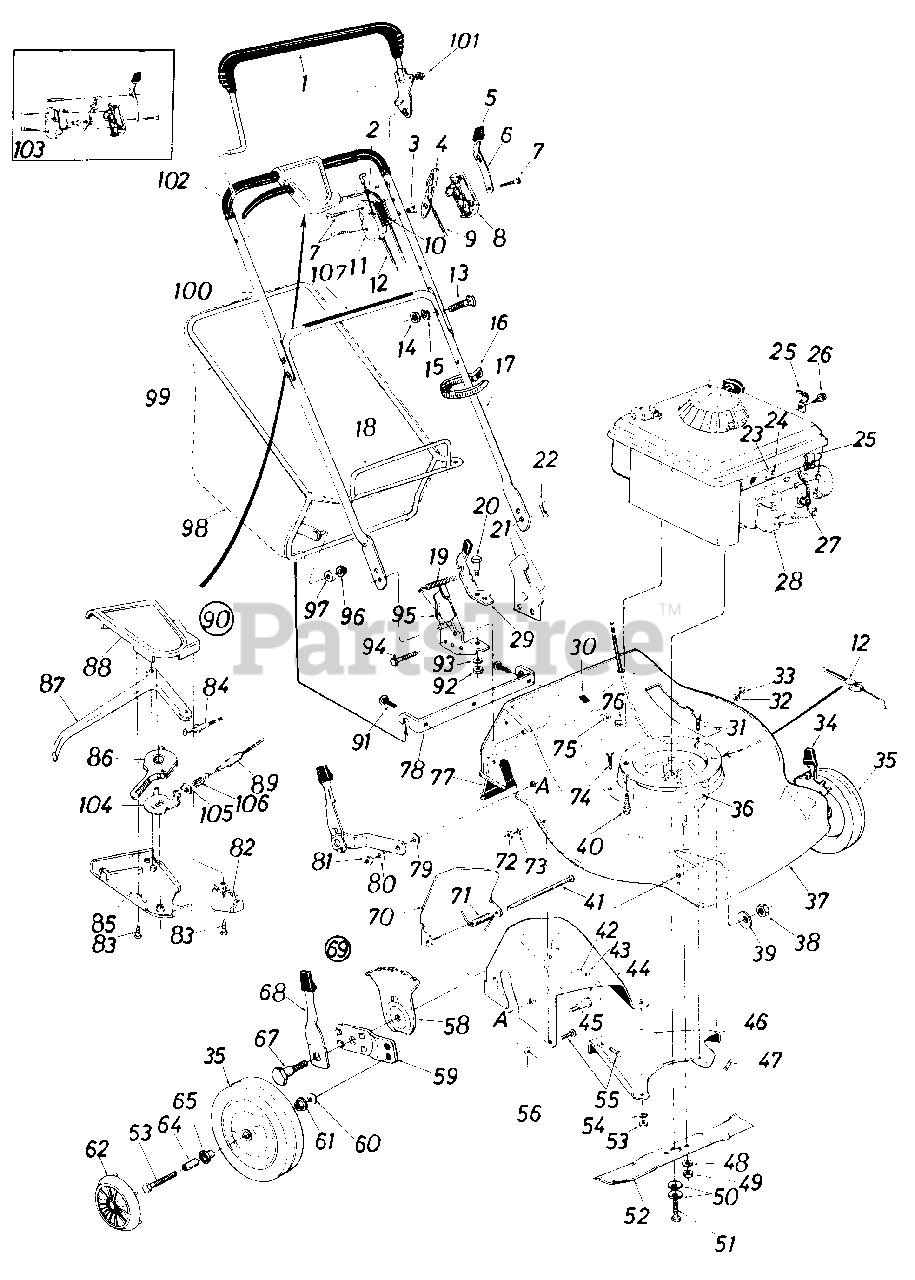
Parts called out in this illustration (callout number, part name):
1	L.H. Bail Ass'y.
2	Lock Pin
3	Control Disc Pin
4	Throttle Control Lever
5	Spring Lever Knob
6	Lockout Spring
7	Truss Mach. Hi-B Tap Scr. #12 x 1.50" Lg.
8	Control Panel Half
9	Throttle Control Wire-58"
10	Control Label
11	Clutch Panel Half
12	Clutch Cable 46" Lg.
13	Carr. Bolt 5/16-18 x 1.38"
14	Hex Nut 5/16-18 Thd.*
15	L-Wash. 5/16 I.D.*
16	Cable Tie
17	Lower Handle (Chrome)
20	Shld. Bolt .437" Dia. x .162
21	Handle Brkt. Ass'y.-L.H.
22	Hairpin Cotter 5/16" Dia.
23	Hex B-Tap Scr. #10 x .62"
24	Casing Clamp
25	Cable Clip
26	Hex B-Tap Scr. #10 x .38"
27	Spark Plug Insulator
28	Engine
29	Catcher Lock Lever w/Knob
31	Hex TT-Tap Scr. 1/4-20 x .75" Lg.
32	L-Wash. 1/4" I.D.
33	Hex Nut 1/4-20 Thd.*
34	Height Adj. Ass'y.-L.H.
35	Front Wheel Ass'y. Comp.
36	Blade/Brake Clutch Ass'y.-Comp.
39	Bell-Wash. .39" I.D. x 1.13"
40	Hex Wash. Hd. TT-Tap Scr. 3/8-16 x 1.0" Lg.
41	Hinge Pin
42	Hex Nut 1/4-20 Thd.*
43	L-Wash. 1/4" I.D.*
44	Rear Chute-R.H.
45	Shld. Bolt.500" Dia.
46	Rear Baffle-L.H.
47	Carr. Bolt 1/4-20 x .50" Lg.*
48	L-Wash. 3/8" I.D.*
49	Hex Nut 3/8-24 Thd.-Gr. 8
50	Bell-Wash. .40" I.D. x .88"
51	Hex Cl-Bolt 3/8-24 x 2.0" Lg. (Grade 8)
52	22" Blade
53	Hex Nut 1/4-20 Thd.*
54	L-Wash. 1/4" I.D.
55	Carr. Bolt 1/4-20 x .50" Lg.
56	Hex Sems Nut 1/4-20 Thd.
58	Height Adj. Plate
59	Wheel Pivot Bar
60	Bell-Wash. .40" I.D. x .88"
61	Bearing
62	Plastic Hub Cap
63	Axle Bolt
64	Spacer
65	Bearing
67	Shld. Bolt .50" Dia. x .430
68	Spring Lever Ass'y. w/ Knob
69	Height Adj. Ass'y.-R.H.
70	Chute Door
71	Torsion Spring
72	Hex Nut 1/4-20 Thd*
73	L-Wash. 1/4" I.D.*
74	Hex Bolt 1/4-20 x .88" Lg.
75	Fl-Wash. .285" I.D. x 1.25"
76	Hex Sems Nut 1/4-20 Thd.
77	Rear Flap
78	Grass Catcher Hitch Brkt.
79	Bell-Wash. .40" I.D. x 1.13"
80	Bell-Wash. .40" I.D. x .88"
81	Hex Jam Nut 3/8-16 Thd.
82	Cable Mounting Cap
83	Flat 'C"Sunk Hd. Tap Scr. #10 x .75" Lg.
84	S.P. Cable-53" Lg.
85	3-Sp. S.P. Control-Lower Cover
86	Shimano 3-Sp. Shift Lever
87	Control Lever
88	3-Sp. S.P. Control-Upper Cover
89	Shimano 3-Sp. Solid Shift Cable
90	Clutch Control Hsg. Comp.
91	Carr. Bolt 1/4-20 x .75" Lg.
92	Hex Nut 5/16-18 Thd.*
93	L-Wash. 5/16" I.D.*
94	Hex L-Wash. Hd. AB-Tap Scr. 1/4" x .62" Lg.
95	Handle Brkt. Ass'y.-R.H.
96	Push Nut 3/8" Rod
97	Plastic Roller
98	Grass Bag (w/o Flip Top)
99	Catcher Upper Frame
100	Upper Handle (Chrome)
101	Push Cap
103	Control Housing Comp.
104	Shimano 3-Sp. Shift Lever Brkt.
105	Shimano 3-Sp. Cable Spring Brkt.
106	Shimano 3-Sp. Cable Mounting Spring
107	Instruction Label
